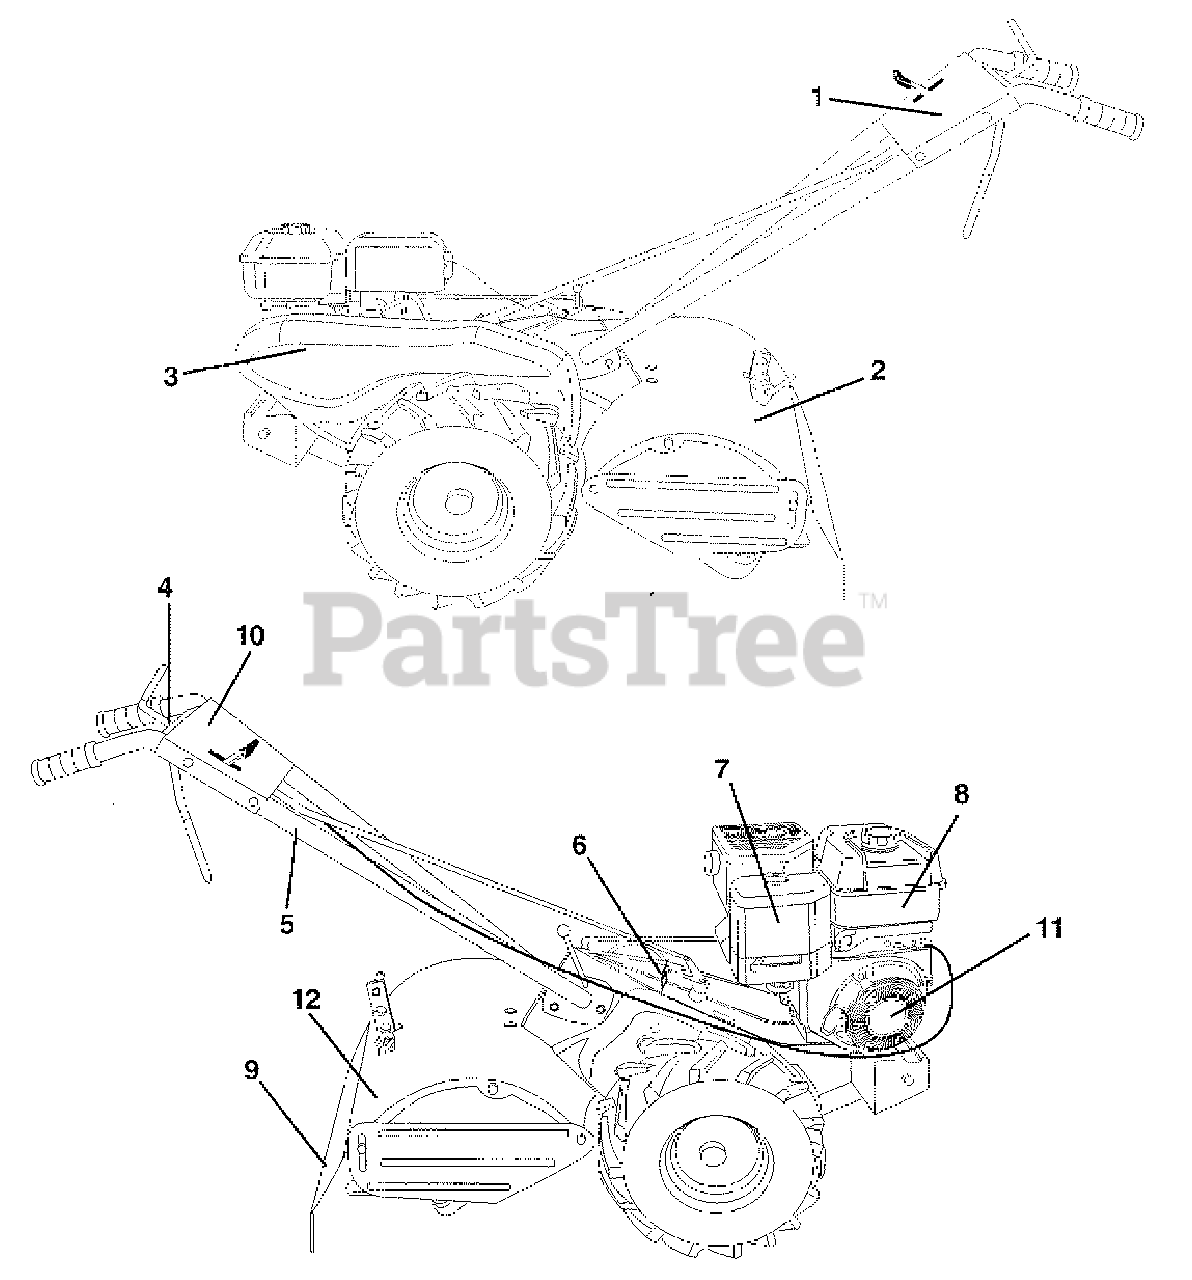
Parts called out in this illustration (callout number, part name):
1	Decal, Logo
2	Decal, Description
3	Decal, Logo
4	Decal, instruction, Tilling
5	Decal, Hand Placement
6	Decal, Shift Indicator
7	Decal, Briggs & Stratton
8	Decai OHV N-IC
9	Decal, Warning, Rotating Tines
10	Decal, Reverse
11	Decal, Rewind Intek
12	Decal, Tine Shield Wrng Dom
12	Manual, Owner's (English)
12	Manual, Owner's (Spanish)
